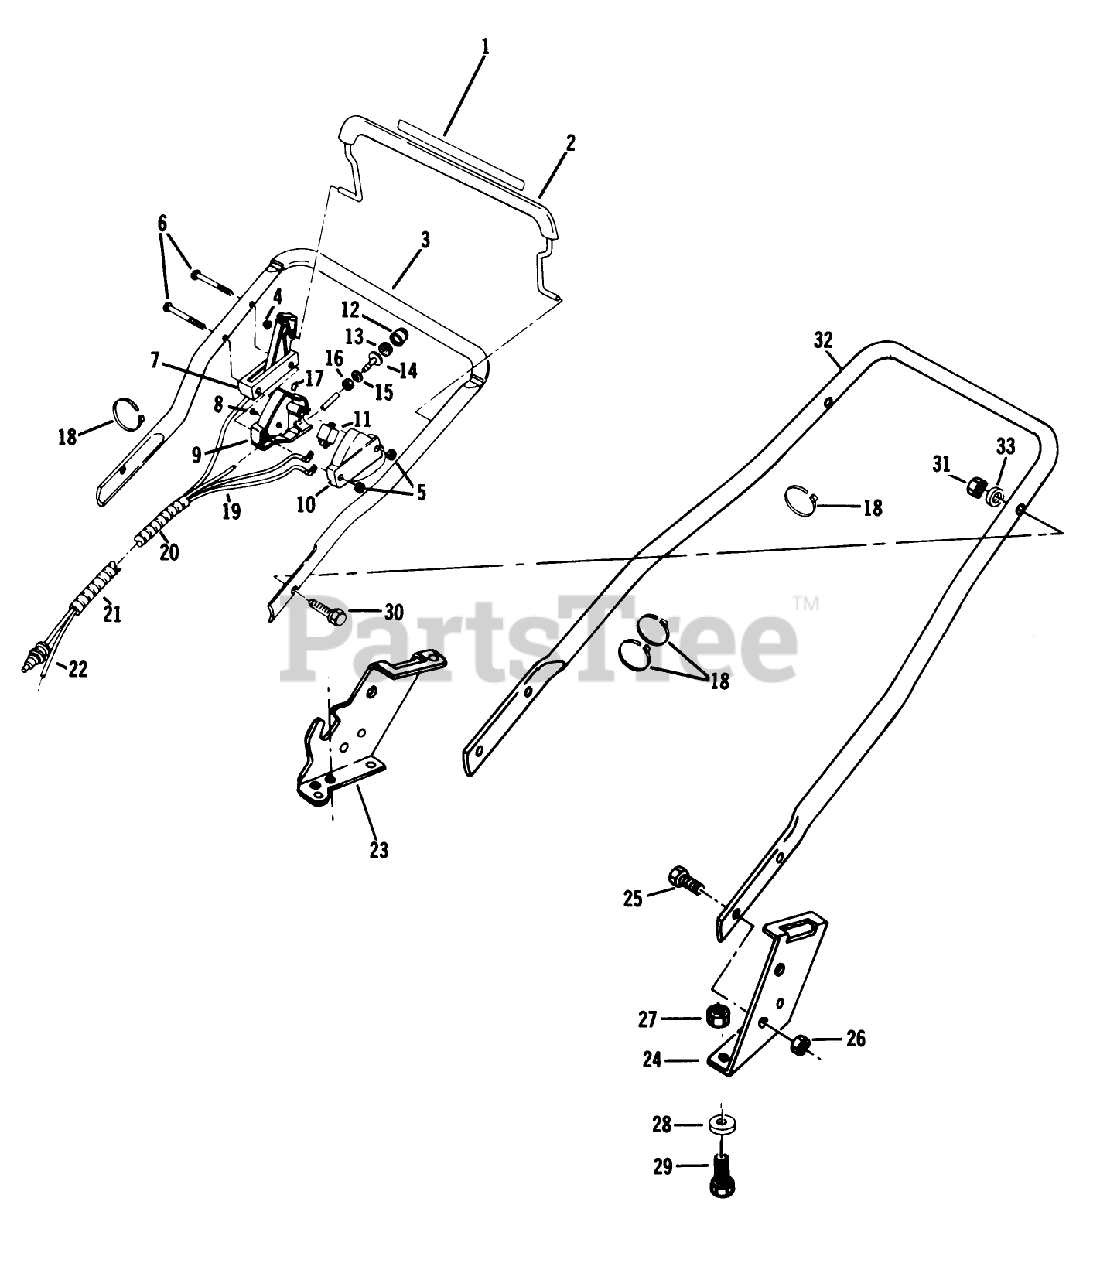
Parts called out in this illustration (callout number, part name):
5	NUT C/LOCK E
11	SWITCH AY
13	FILTER S
16	LOCKNUT S
26	NUT-JAM, LOCKING
27	NUT-LOCK F
31	NUT-LOCK F
33	WASHER-CURVED
